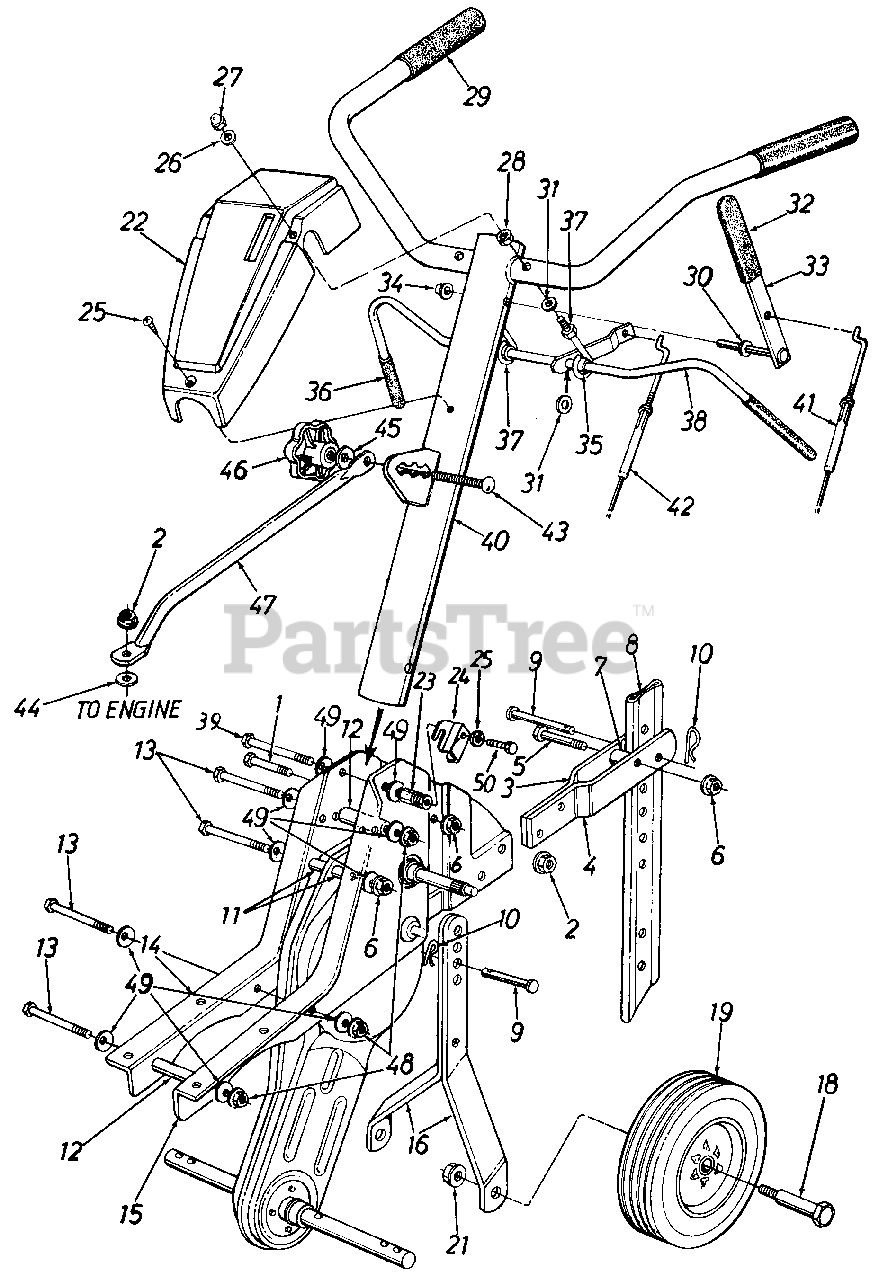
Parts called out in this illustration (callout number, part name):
1	Hex Bolt 5/16-18 x 1.25" Lg.
2	Hex Flange L-Nut 5/16-18 Thd. (Gr. 5)
5	Hex Bolt 5/16-18 x 1.5" Lg.
6	Hex Flange L-Nut 5/16-18 Thd. (Gr. 5)
7	Spacer .32" I.D. x .75" O.D.
9	Clevis Pin .375" I.D. x 1.75" Lg.
10	Internal Cotter Pin
11	Spacer .326" I.D. x .47" O.D.
12	Spacer .322" I.D. x .44" I.D.
13	Hex Bolt 5/16-18 x 2.75" Lg.
19	Wheel Ass'y. 8" x 1.75"
21	Hex Flange L-Nut 3/8-16 Thd. (Gr. 5)
22	Handle Cover w/Reverse
23	Spec. Hex Nut
25	L-Wash. 5/16" I.D.
26	Fl-Wash. .266" I.D. x .625" O.D.
27	Hex L-Stop Nut 1/4-28 Thd.
28	Hex Nut 1/4-28 Thd.
29	Grip - Handle
30	Fl-Wash. .344" I.D. x .62" O.D.
31	Fl-Wash. .385" I.D. x .62" O.D.
32	Grip - Reverse Lever
33	Reverse Handle Ass'y.
34	Cap Speed Nut
35	Plastic Bushing .38" I.D.
36	Grip - Clutch
37	Clutch Handle Eye Bolt
42	Clutch Control Cable - Forward
43	Carr. Bolt 5/16-18 x 1" Lg. (Special)
44	Fl-Wash. .344" I.D. x 1.12" O.D.
45	Bell-Wash. .345" I.D. x .88" O.D.
46	Hand Knob
49	Bell-Wash. .345" I.D. x .88" O.D.
